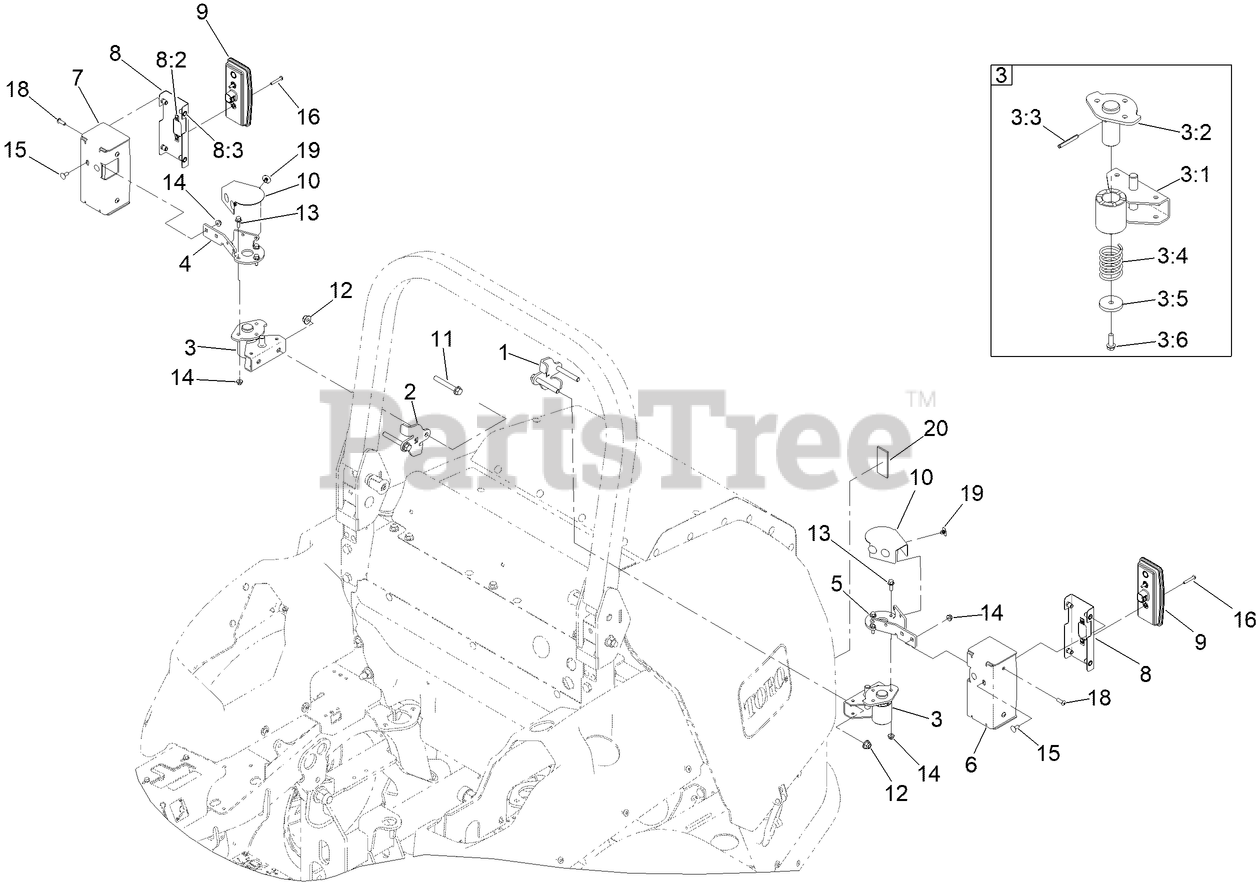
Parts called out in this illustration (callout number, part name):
1	MOUNT-TURN, LH
2	MOUNT-TURN, RH
3	BRACKET-PIVOT, ASM
3:1	PIVOT BRACKET ASM [BLACK]
3:3	PIN-ROLL
3:4	SPRING-COMPRESSION
3:5	WASHER 34 DIA X 7 DIA X 5 THK
3:6	SCREW-HWH
4	MOUNT-LIGHT, RH
5	MOUNT-LIGHT, LH
6	HOUSING-LIGHT, LH
7	HOUSING-LIGHT, RH
8	INNER MOUNT ASM
8:2	NUT-SPEED
8:3	NUT-CLINCH, HEX
9	LIGHT-REAR TAIL/STOP/TURN
10	COVER-MOUNT
11	SCREW-HHF
12	NUT-HF, NI
13	SCREW-HHF
14	NUT-HF
15	SCREW-CARR
16	SCREW-PPH
18	SCREW-HSBH
19	RIVET-PLASTIC
20	REFLECTOR-ADHESIVE
